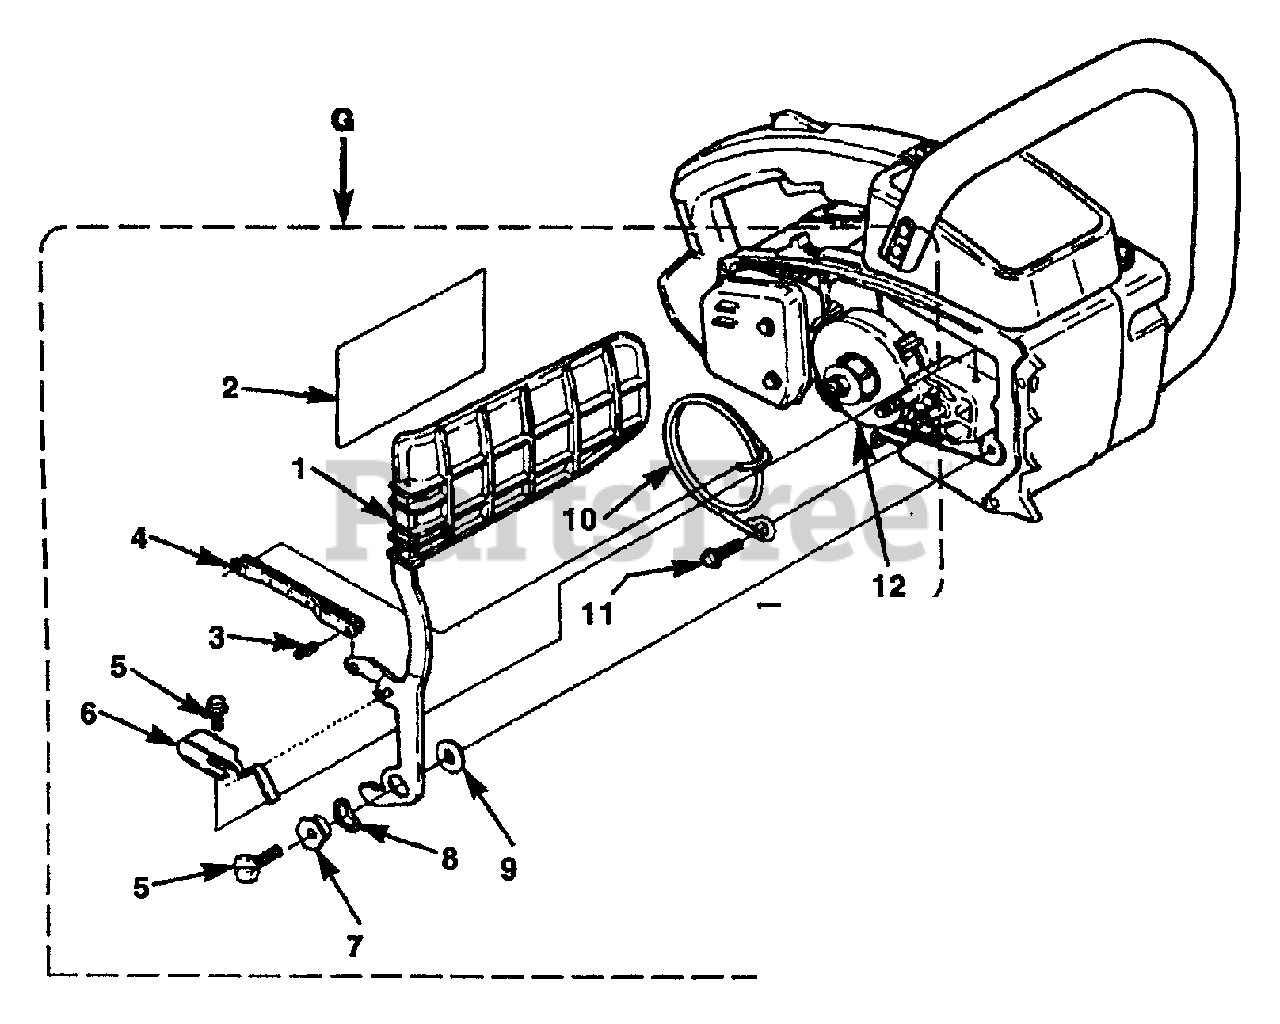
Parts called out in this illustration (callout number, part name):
1	HAND GUARD
2	PIN-Roll
3	DECAL-Warning
4	LINK-Pivot
5	SCREW-Hex Cap (1/4-20 X 5/8")
6	CLIP-Retaining
7	CAP-Brake Lever
8	WASHER-Curved
9	WASHER-Thrust
10	BAND-Brake
11	SCREW- Hex (10-24 X 5/8")
12	SPROCKET & DRUM
G	CHAIN BRAKE KIT
